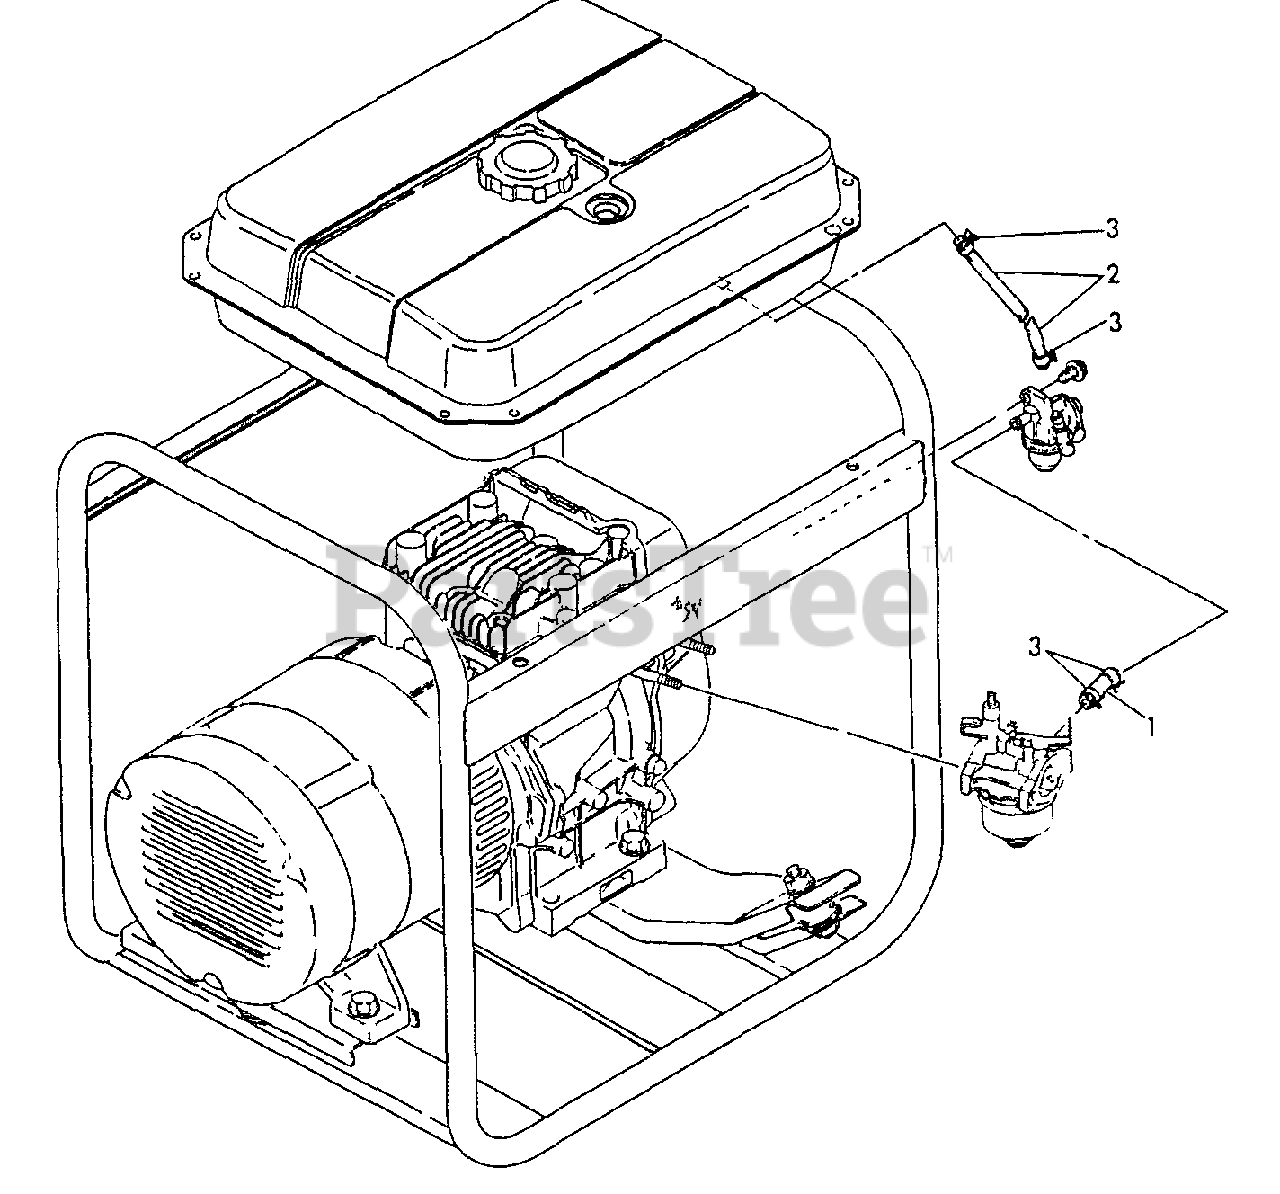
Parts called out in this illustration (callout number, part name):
1	PIPE, FUEL
2	PIPE, FUEL
3	CLAMP
